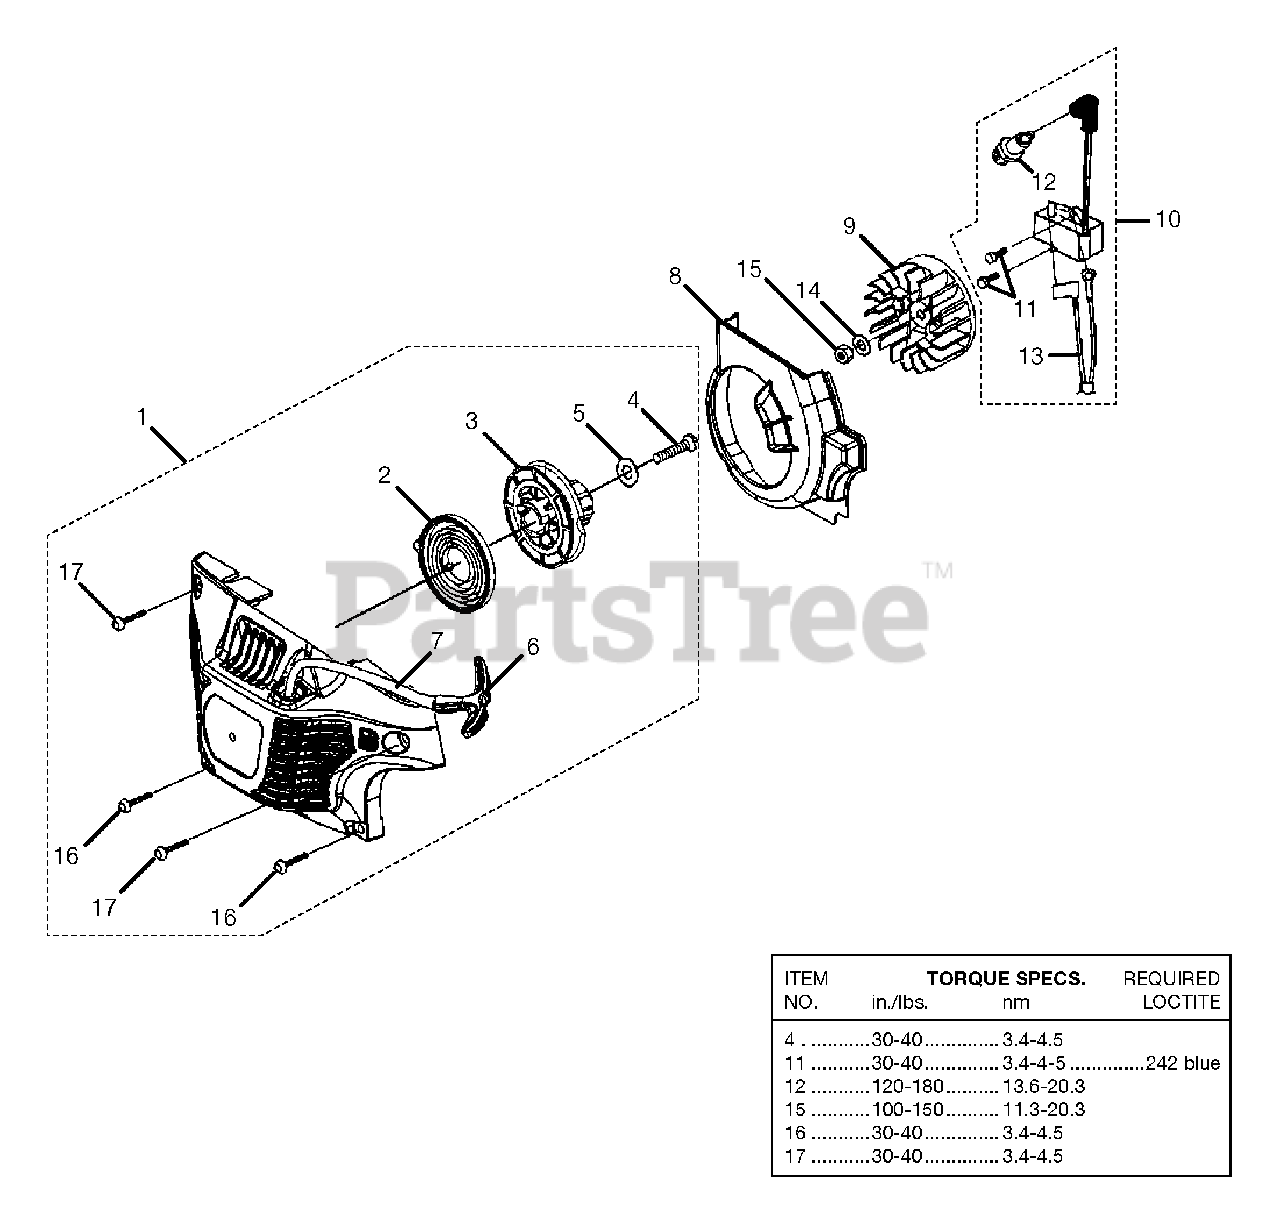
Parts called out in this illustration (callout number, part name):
1	STARTER COVER ASSY., W/EYELET
2	SPRING & CONTAINER
3	PULLEY, STARTER
4	SCREW (10-14 x 5/8 in.)
6	GRIP, STARTER
7	ROPE, STARTER (46 in.)
8	BAFFLE
9	ROTOR W/STARTER PAWL
10	IGNITION KIT
11	SCREW (8-32 x 5/8 in.)
12	SPARK PLUG
13	IGNITION SWITCH HARNESS
15	NUT
16	SCREW (10-14 x 7/8 in.)
17	SCREW (10-14 x 5/8 in.)
